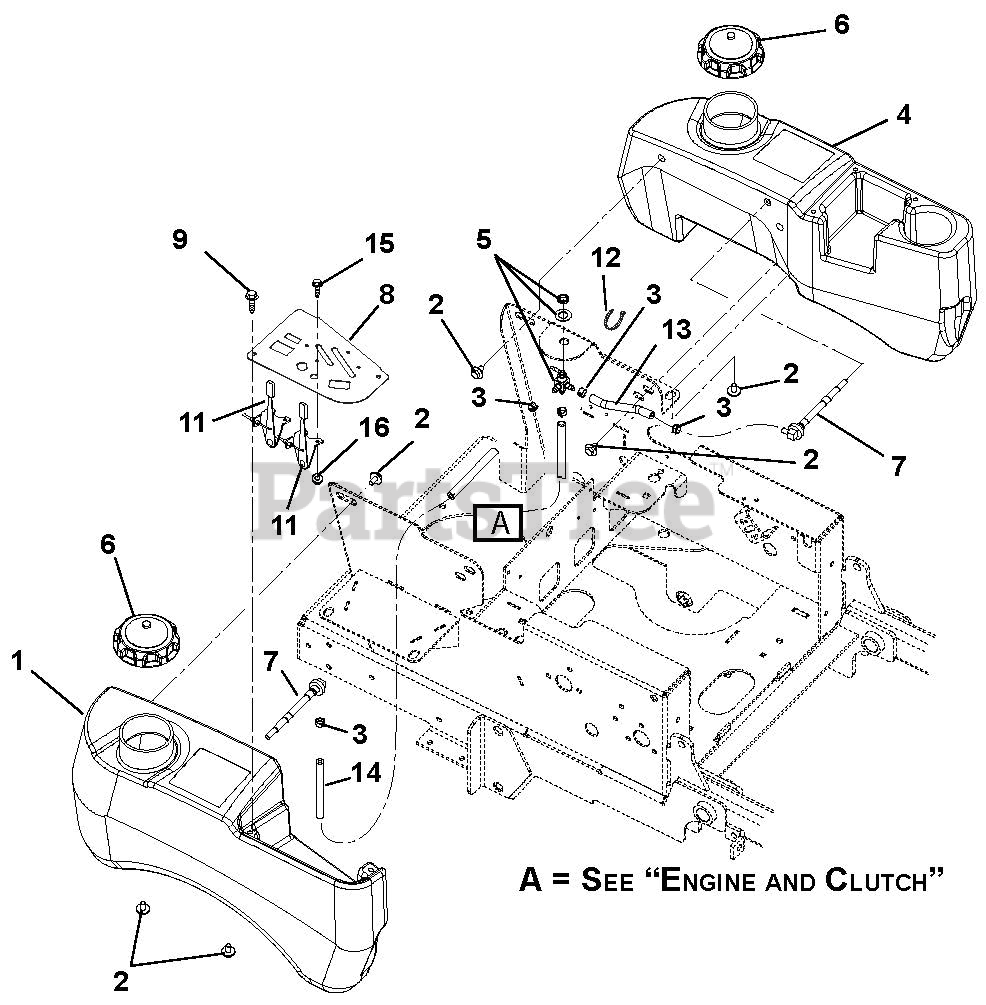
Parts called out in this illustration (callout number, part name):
1	Tank, Fuel Right Hand
2	Bolt, SEMS .31-18 x .62
3	Clamp, Fuel Line
4	Tank, Fuel Left Hand
5	Valve, Fuel
6	Cap, Fuel Non-Vent Autolock
6	Cap, Fuel Vent-In Autolock
7	Assembly, Tank Fuel Pick-up
8	Panel, Control
9	Screw, Machine 10-24 x .50 Stainless
10	Cable, Throttle
11	Cable, Control
12	Cable Tie
13	Hose, .25 Low-PERM Bulk Gas
14	Hose, .25 Low-PERM Bulk Gas
15	Screw, Machine 10-24 x .50 Hex Washer Head
16	Nut, Locking-Nylon 10-24 with Insert
